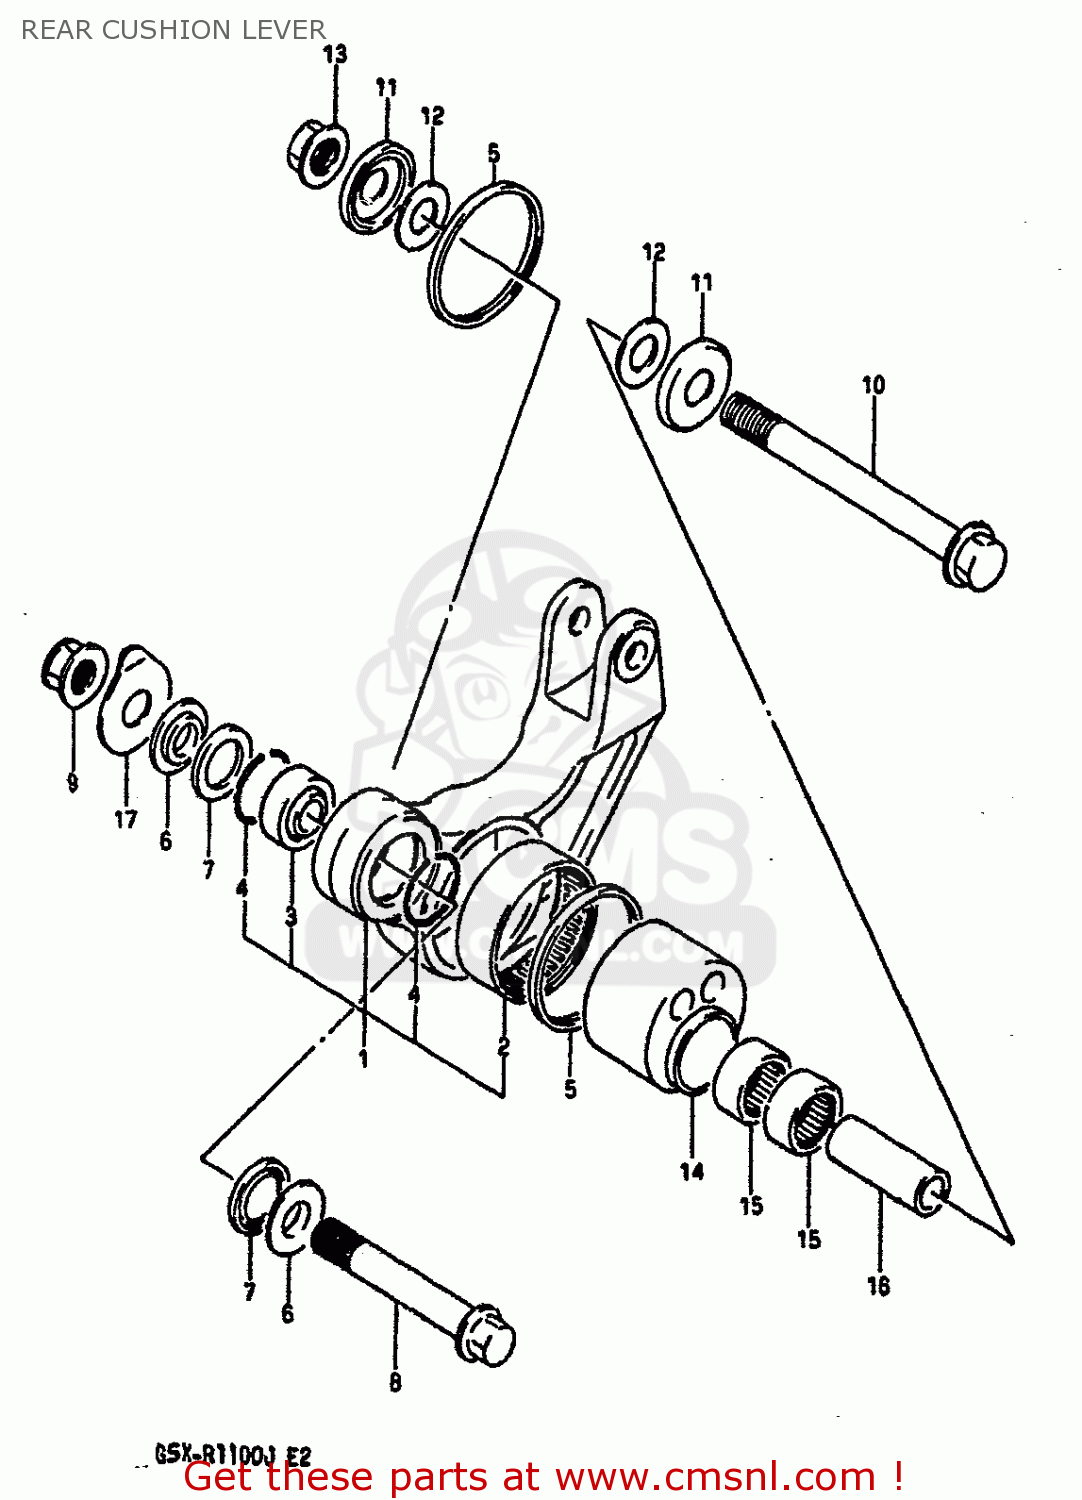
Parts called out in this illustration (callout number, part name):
1	LEVER SET,REAR CUSHION
2	BEARING(45X52X20)
3	BEARING(12X26X16)
4	RING,STOPPER
5	SEAL,ECCENTRIC LVR DUST CTR
6	SPACER,RR CUSHION ROD
7	SEAL,RR CUSHION ROD DUST
8	BOLT,RR CUSHION LEVER FR
9	NUT 12MM
10	BOLT(12X105)
11	COVER,REAR SWING ARM DUST
12	WASHER
13	NUT 12MM
14	ECCENTRIC SPACER,REAR SUSPENSION
15	BEARING(17X24X15)
16	SPACER,ECCENTRIC LVR CTR
17	SHIM,REAR CUSHION LEVER
